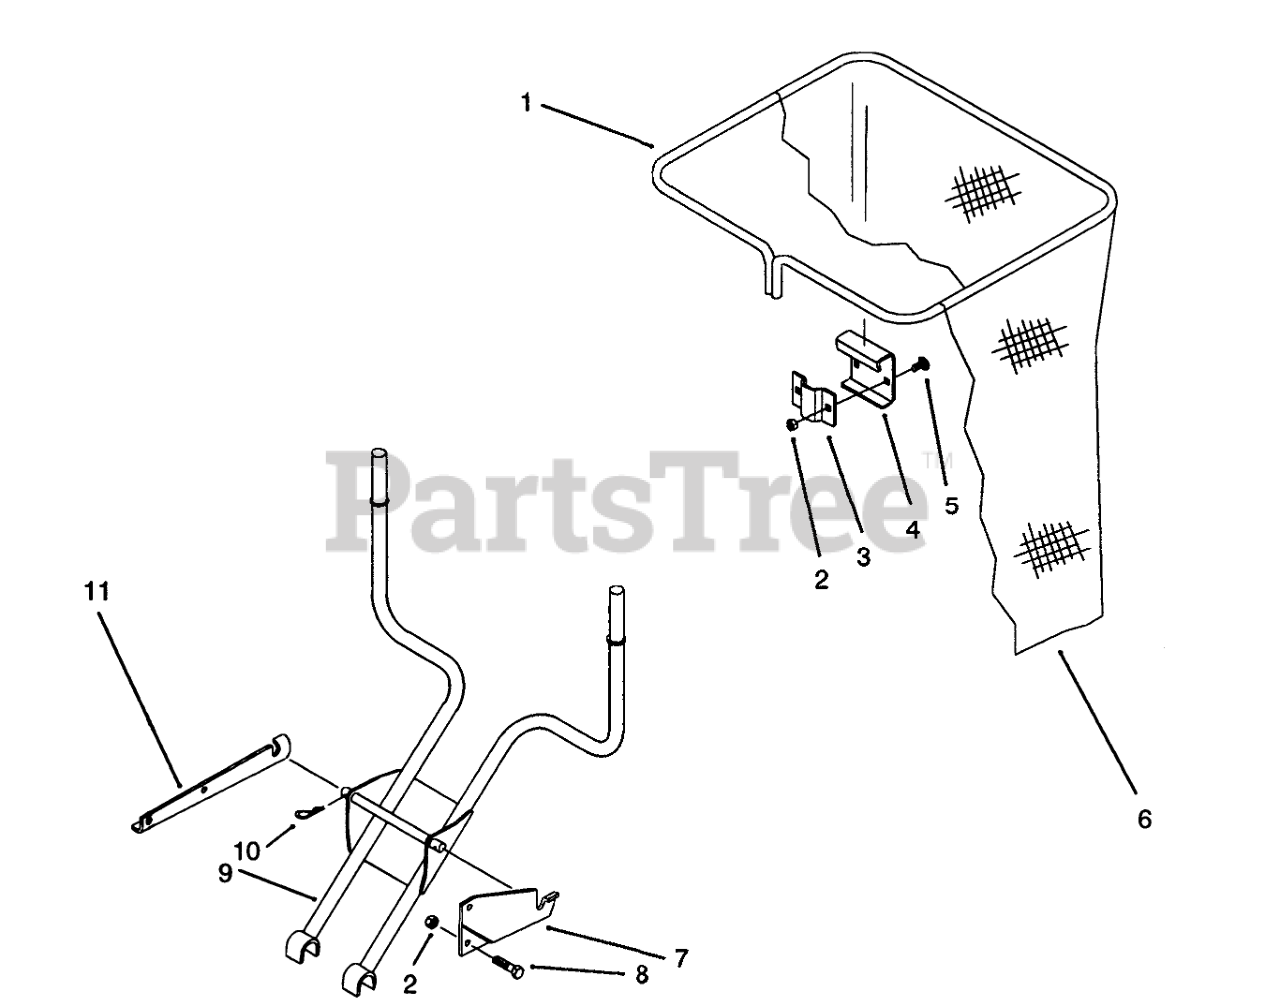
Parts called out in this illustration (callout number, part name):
1	Bag Frame
2	NUT-LOCK, NI
3	Clamp
4	Bag Hanger
5	BOLT-CARR
6	Bag
7	SUPPORT-BAGGER L. B
8	SCREW-HH
9	WLDMT-QUICK ATTAC B
10	Hairpin
11	SUPPORT-BAGGER R. B
